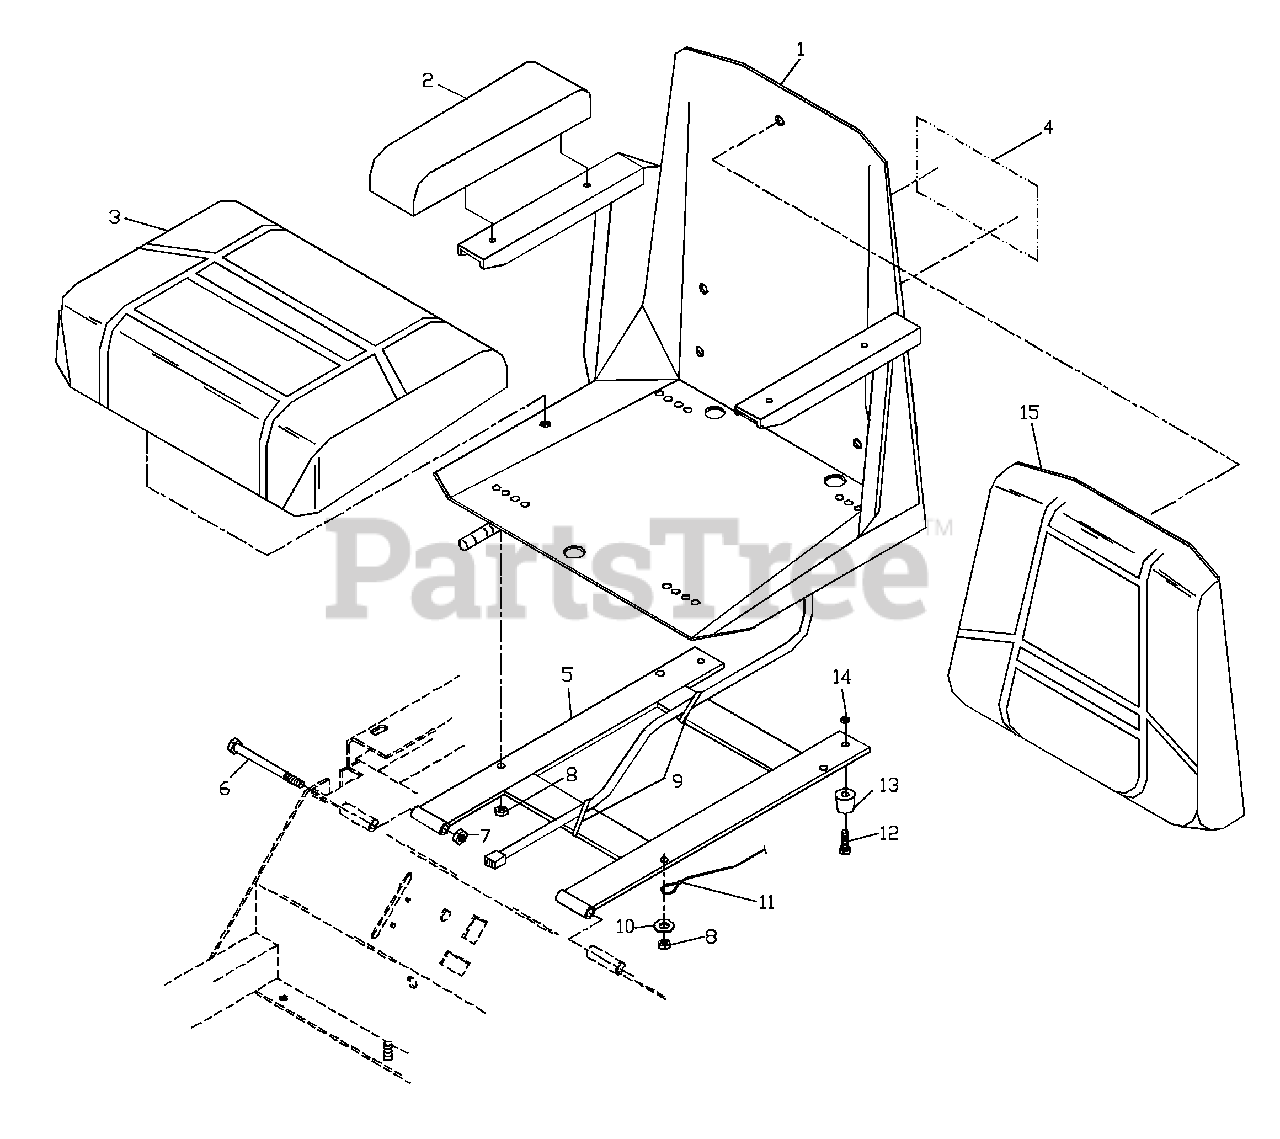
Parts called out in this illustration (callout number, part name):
1	COMPLETE-SEAT
2	ARM REST CUSHION
3	SEAT CUSHION W/SWITCH
4	DECAL, CROWN
5	SEAT MOUNT
6	HCS 3/8C X 4 1/2
7	NUT 3/8C CENTERLOCK
8	NUT 5/16C CENTERLOCK
9	PLASTIC TIE
10	5/16 FLAT WASHER
11	SEAT LANYARD
12	#10-24 X 1/2 SLOTTED SCREW
13	SEAT BUMPER
14	#10-24 NYLOC NUT
15	SEAT BACK CUSHION
